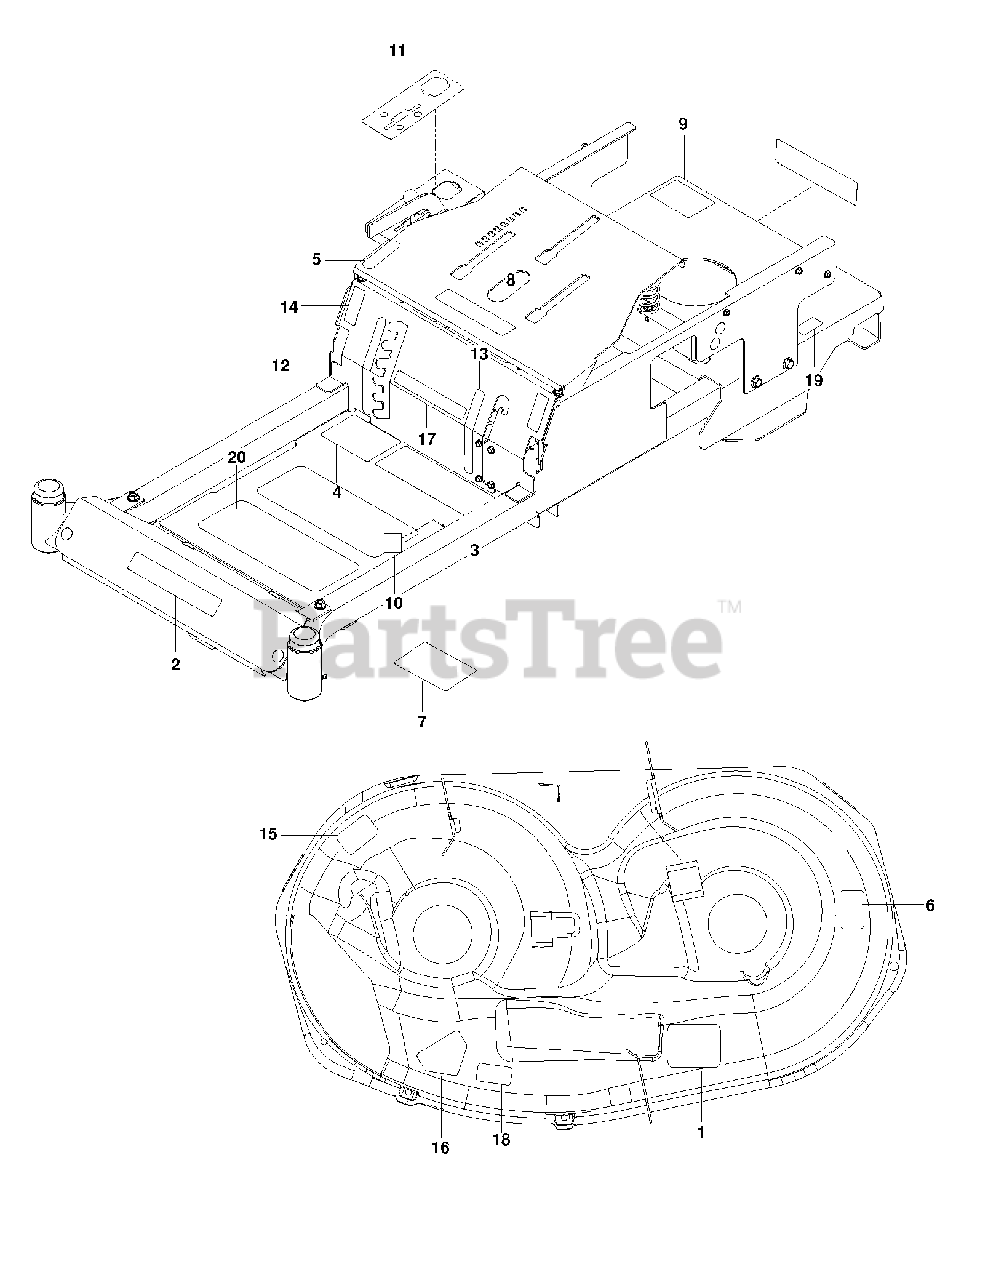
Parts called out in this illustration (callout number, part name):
1	DECAL, BELT ROUTING
3	DECAL, SAFETY WARNING
5	DECAL, PARK BRAKE
6	DECAL, 42
7	DECAL, SERVICE
9	DECAL, DO NOT MOUNT
11	DECAL, CONTROL PANEL
12	DECAL, DECK HEIGHT
13	DECAL, BLADE ENGAGEMENT
14	DECAL, MOTION CONTROL
16	DECAL, CPSC
17	DECAL, SPEEDZTR 6.5"
18	DECAL, EURO SEVERING
19	DECAL, ECM, AUSTRALIA
20	ANTI-SKID PAD
